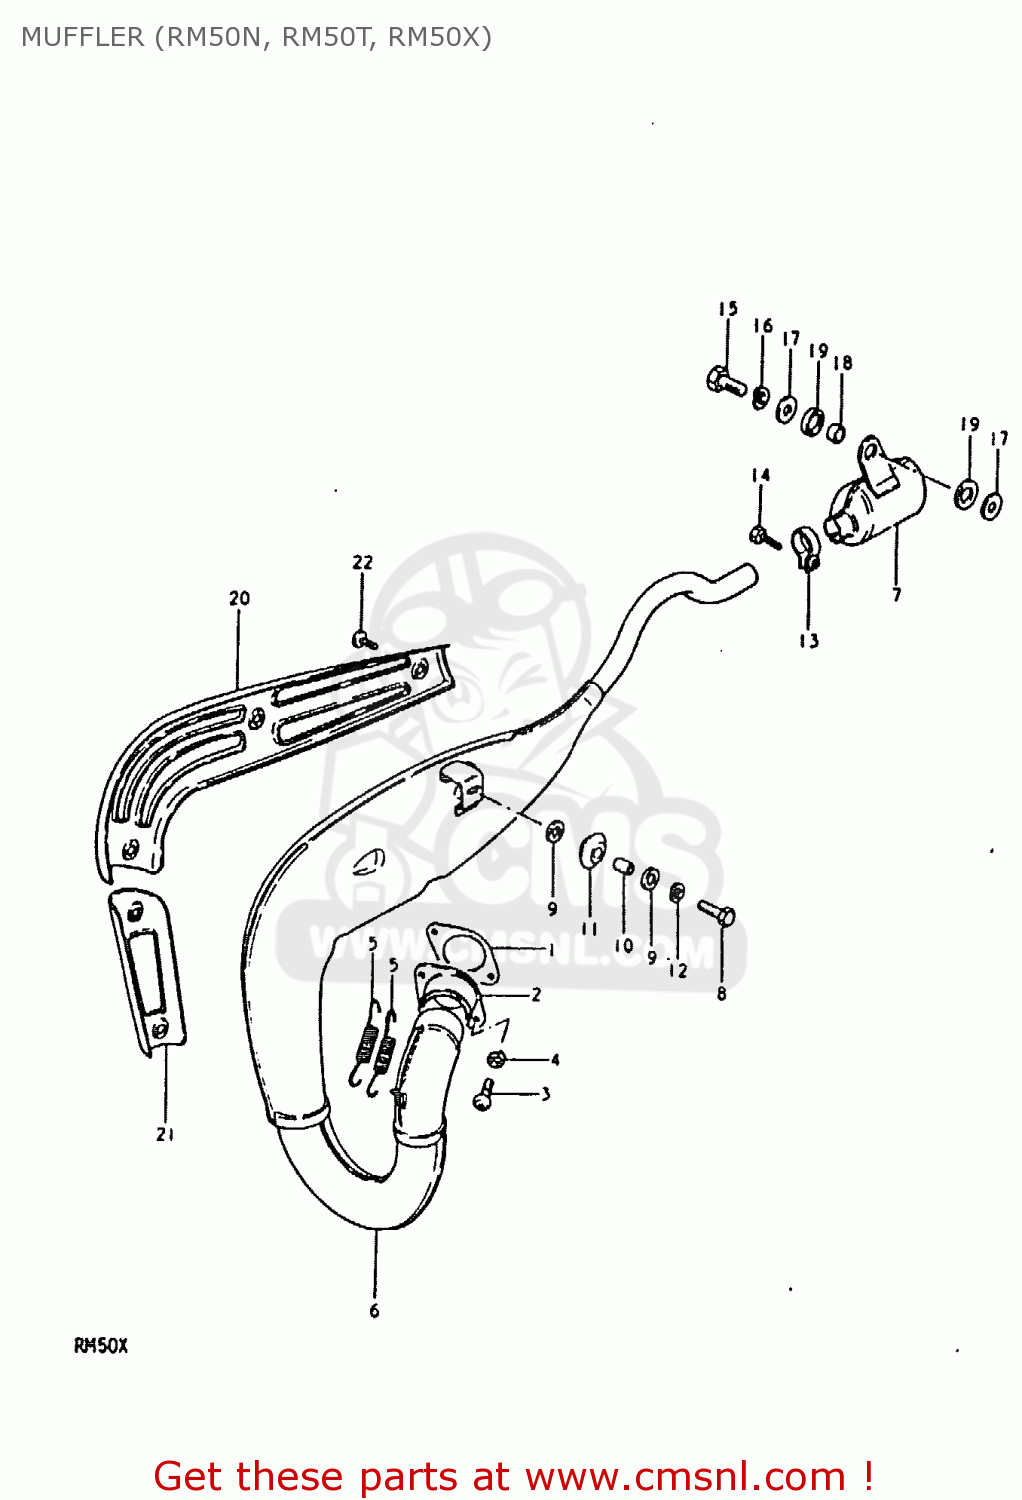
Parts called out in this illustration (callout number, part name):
1	GASKET,EXHAUST PIPE (MCA)
2	PIPE,CENTER EXHAUST
3	SCREW
4	LOCK WASHER
5	SPRING
6	BODY,MUFFLER
7	BODY,MUFFLER
8	BOLT (8X30)
9	WASHER (8.7X22X2)
10	SPACER (8X12X15)
11	DAMPER,MUFFLER,FR
12	LOCK WASHER
13	CLAMP
14	BOLT(6X20)
15	BOLT
16	LOCK WASHER
17	WASHER
18	SPACER (8.6X13.8X9)
19	CUSHION
20	COVER,MUFFLER NO.1
21	COVER,MUFFLER
22	SCREW
